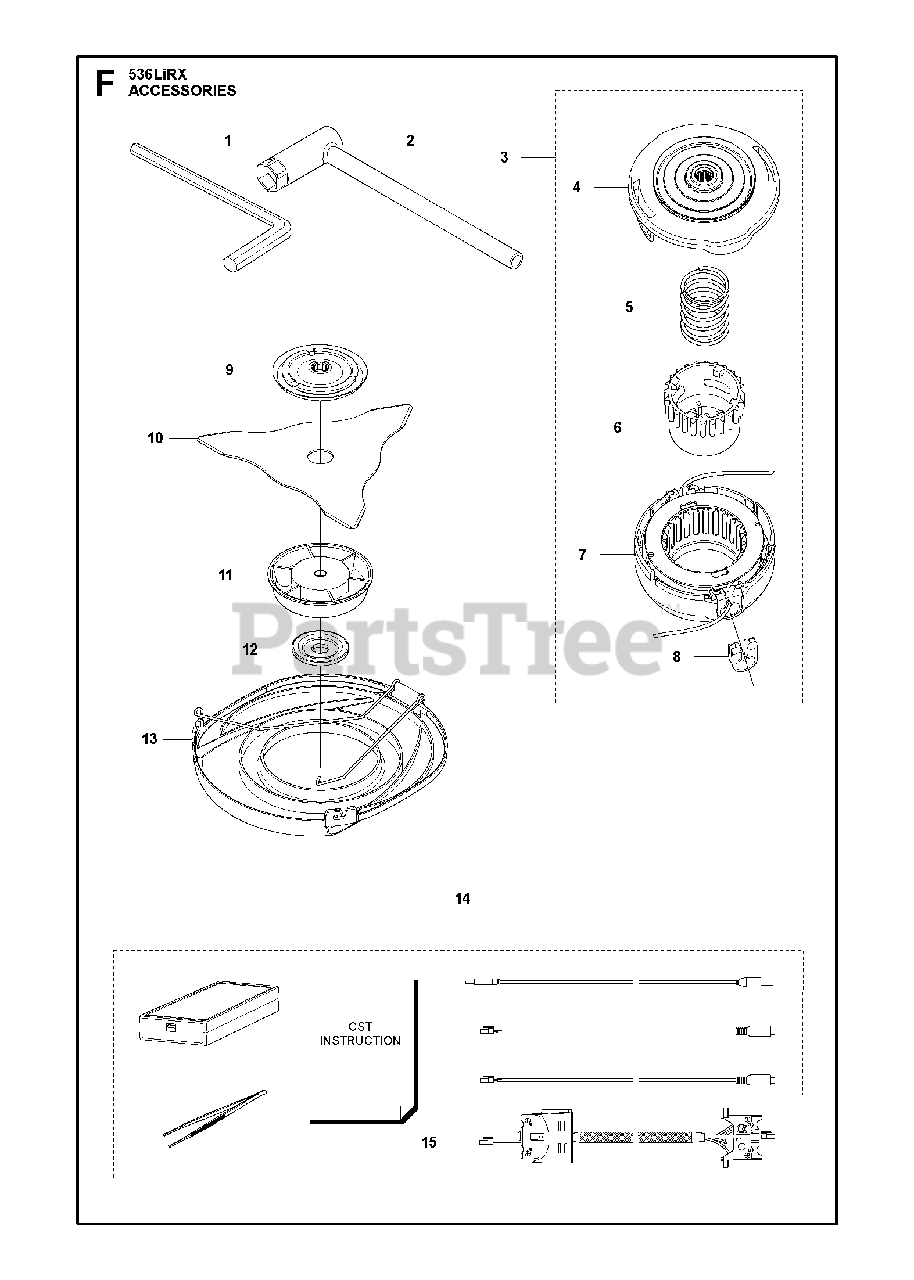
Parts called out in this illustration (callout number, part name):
2	COMBI WRENCH
3	Trimmer Head, T25 10mm
4	HOUSING ASSY
5	SPRING
6	KNOB
7	COVER
8	EYELET
9	DRIVER ASSY
10	BLADE 255-3 1"
11	SUPPORTING CUP
12	SUPPORT FLANGE
13	BLADE GUARD TRANSPORT
14	DIAGNOSTIC TOOL KIT
15	WIRING ASSY
